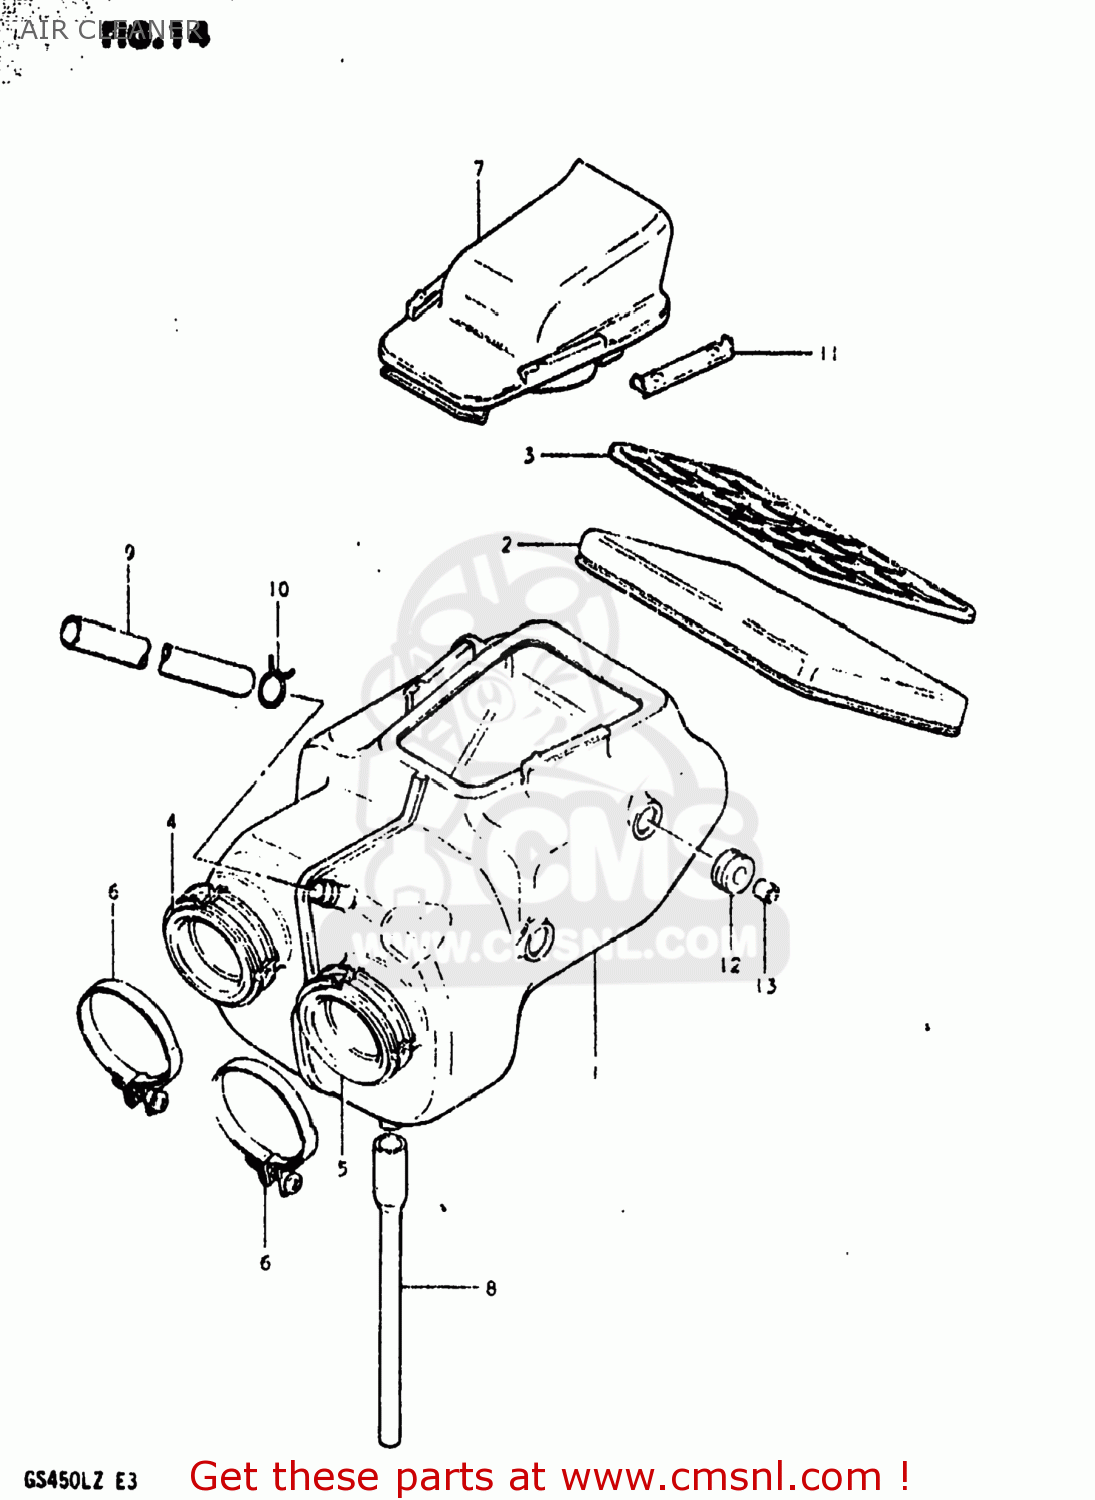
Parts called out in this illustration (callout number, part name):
1	CLEANER ASSEMBLY,AIR
2	FILTER
3	HOLDER NO.2
4	OUTLET,R
5	OUTLET,L
6	CLAMP
7	CAP
8	DRAIN TUBE
9	TUBE,BREATHER
10	CLAMP
11	SLIDER
12	CUSHION
13	SPACER(6.1X9X7.5)
